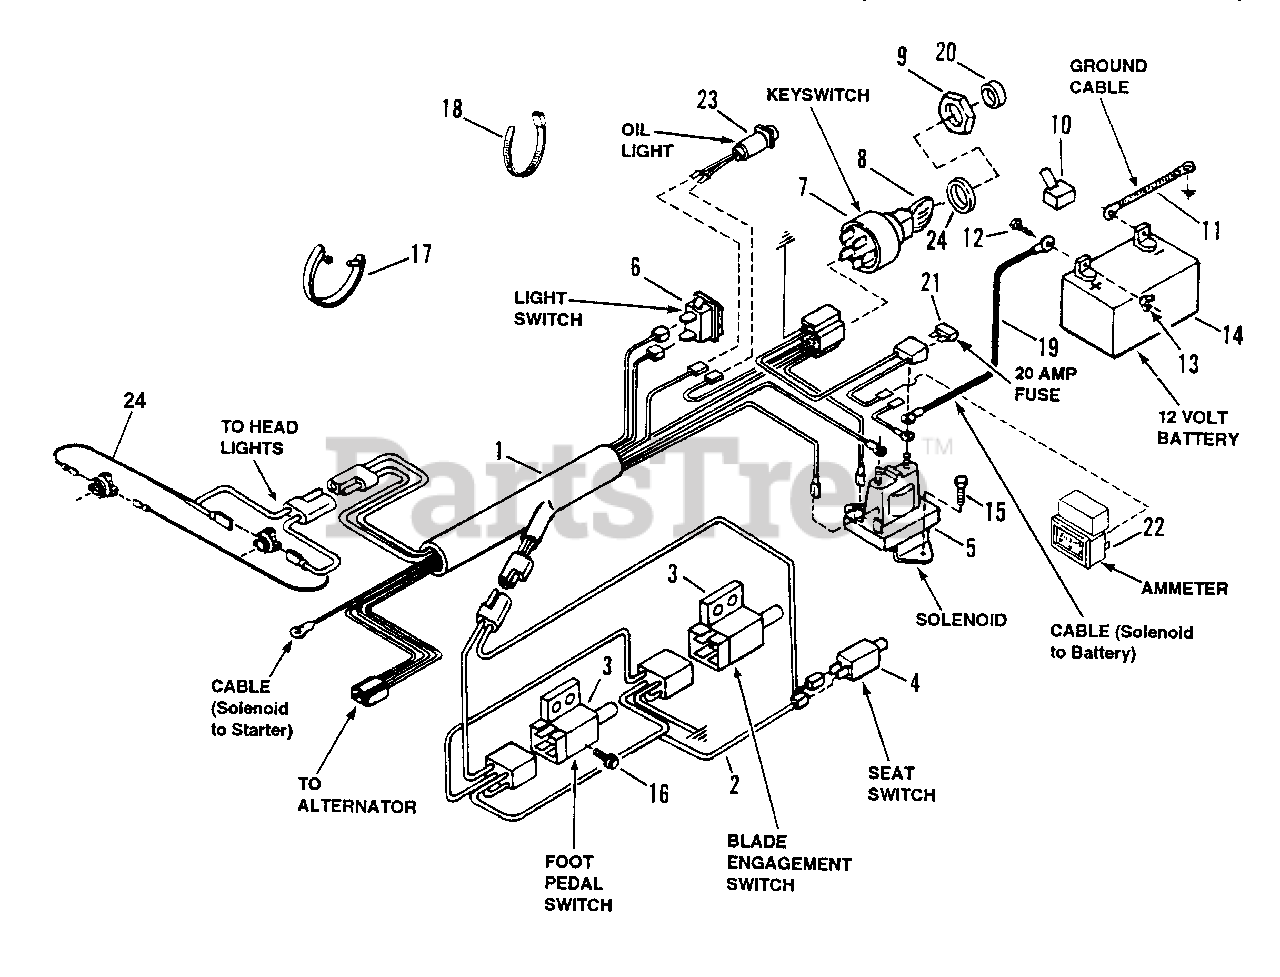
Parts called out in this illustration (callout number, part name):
1	HARNESS, Wiring (Kohler Engine)
2	HARNESS, Interlock
3	SWITCH, Clutch & PTO (NC/NO)
4	SWITCH, Seat (NC)
5	SOLENOID
6	SWITCH, Light
7	SWITCH, Key
8	KEY, Switch (With Cover)
9	NUT, 5/8-32 Hex
10	COVER, Positive Terminal
11	CABLE, Negative 15" 8 AWG Black
12	BOLT, 1/4-20 x 3/4" Carriage
13	NUT, 1/4-20 Wing
14	KIT, Battery
15	SCREW, 1/4-20 x 1/2" Self-Tapping
16	SCREW, #10-24 x 1/2" Hex Washer Self-Tap (Torx)
17	TIE, Wire
18	TIE, Cable 7"
19	CABLE, Positive 11" 8 AWG Red
20	BEZEL
21	FUSE, 20 Amp
22	AMMETER
23	OIL LIGHT
24	HARNESS, Headlight M&G Sockets
